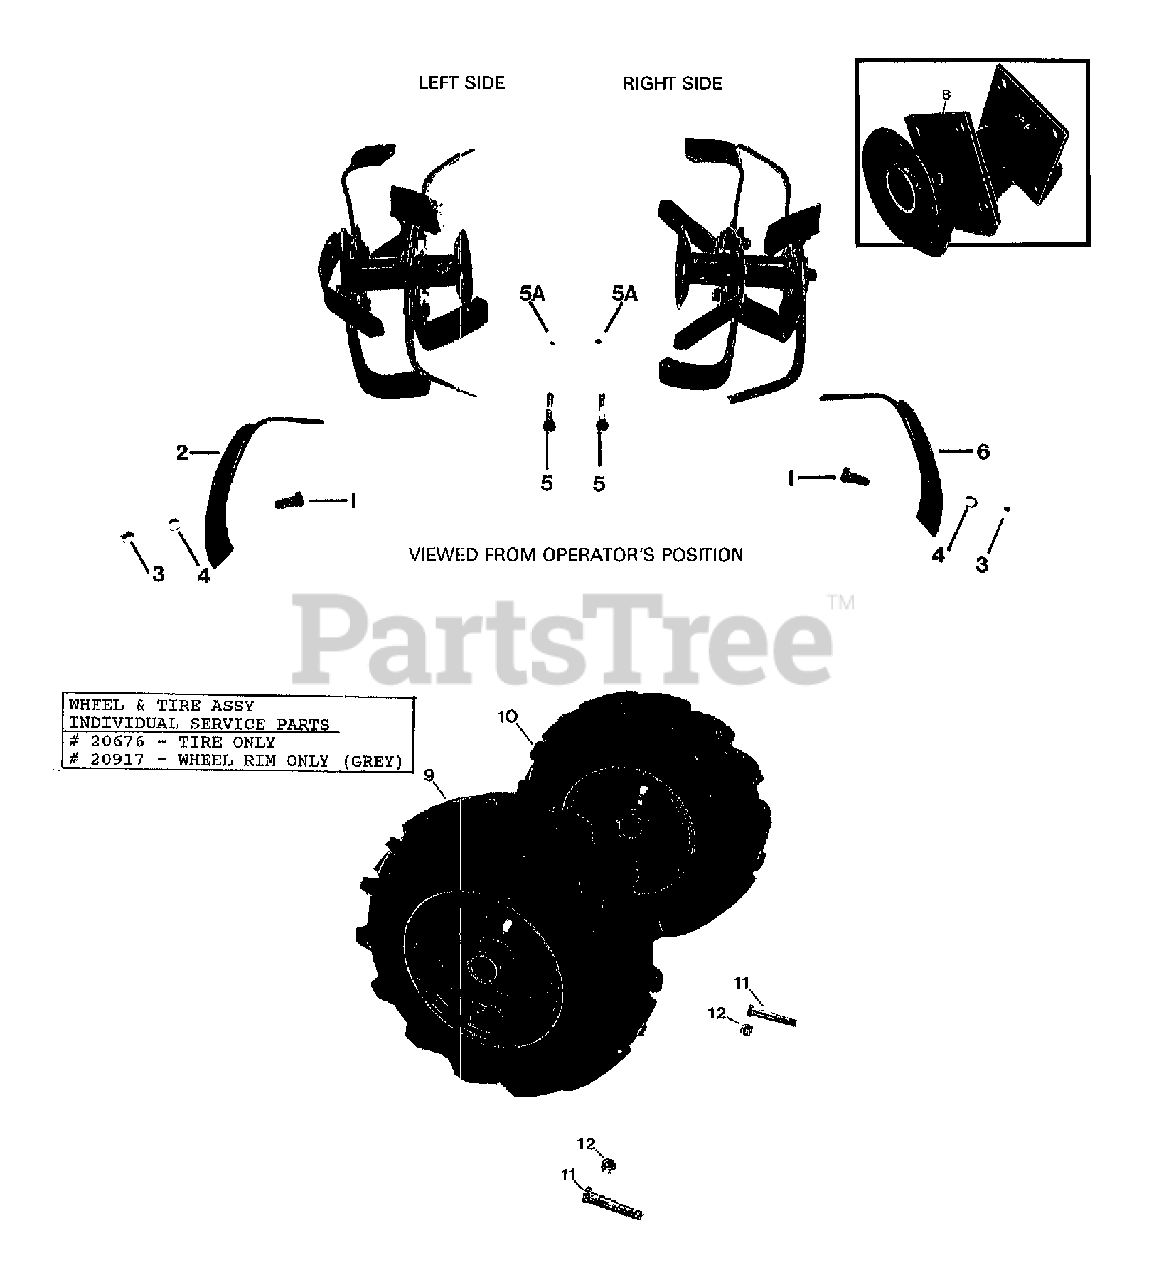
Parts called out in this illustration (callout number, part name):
1	BOLT-hex head, 3/8"-16 x 1", grade 5, tine mounting
2	BOLO TINE-single,
3	NUT- hex, 3/8"-16
4	LOCKWASHER-3/8"
5	BOLT- hex head, 3/8"-16 x 2",grade 8 (holder to tiller shaft)
5A	LOCKNUT-hex, 3/8"-16
6	BOLO TINE-single,
8	TINE HOLDER-
9	WHEEL & TIRE ASSEMBLY-left side, 4.10 x 6" tire mounted on 6" wheel, tubeless pneumatic (10-20 lbs. air required), tractor tread
10	WHEEL & TIRE ASSEMBLY- right side, same specs. as above
11	BOLT-5/16"-18 x 2" (Grade 5), secures wheel hub to wheel shaft
12	LOCKNUT-5/16"-18
